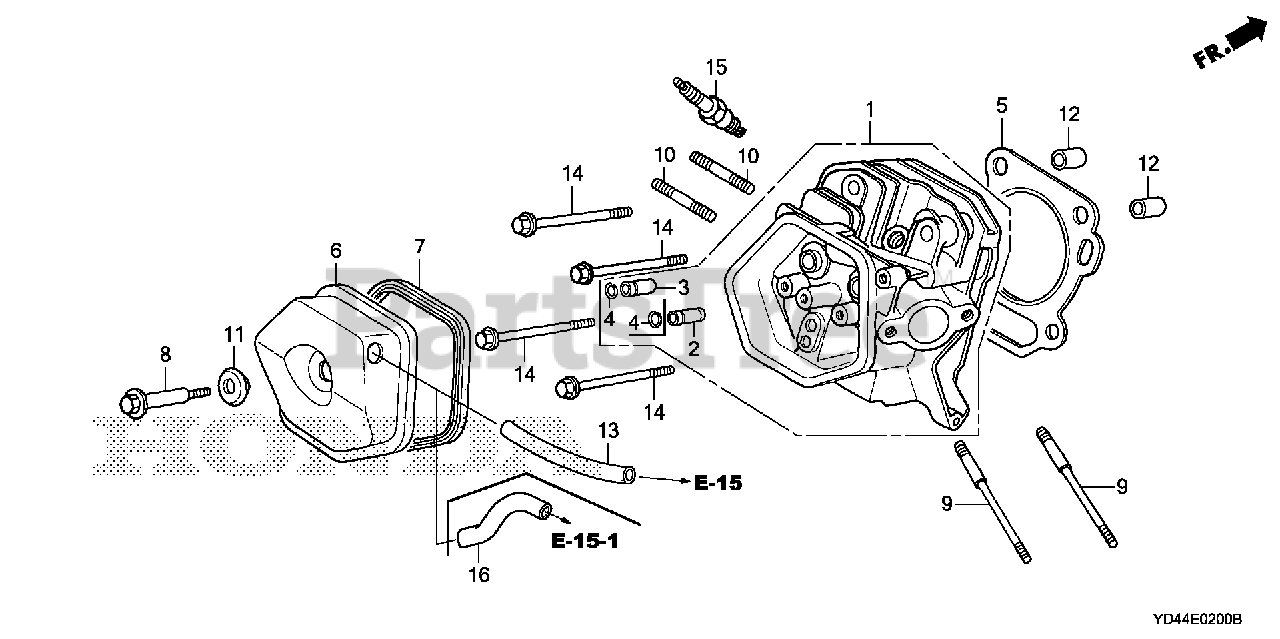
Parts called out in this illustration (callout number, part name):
1	CYLINDER HEAD
2	GUIDE, VALVE (OS)
3	GUIDE, EX. VALVE (OS)
4	CLIP, VALVE GUIDE
5	GASKET, CYLINDER HEAD (NIPPON LEAKLESS)
6	COVER, HEAD
7	GASKET, CYLINDER HEAD COVER
8	BOLT, HEAD COVER
9	BOLT, STUD (8X131.5)
10	BOLT 2, STUD (8X32)
11	WASHER, HEAD COVER
12	PIN A, DOWEL (12X20)
14	BOLT, FLANGE (10X80)
15	SPARK PLUG (BPR5ES) (NGK)
15	SPARK PLUG (W16EPR-U) (DENSO)
15	SPARK PLUG (BPR6ES) (NGK)
15	SPARK PLUG (W20EPR-U) (DENSO)
16	TUBE, BREATHER
